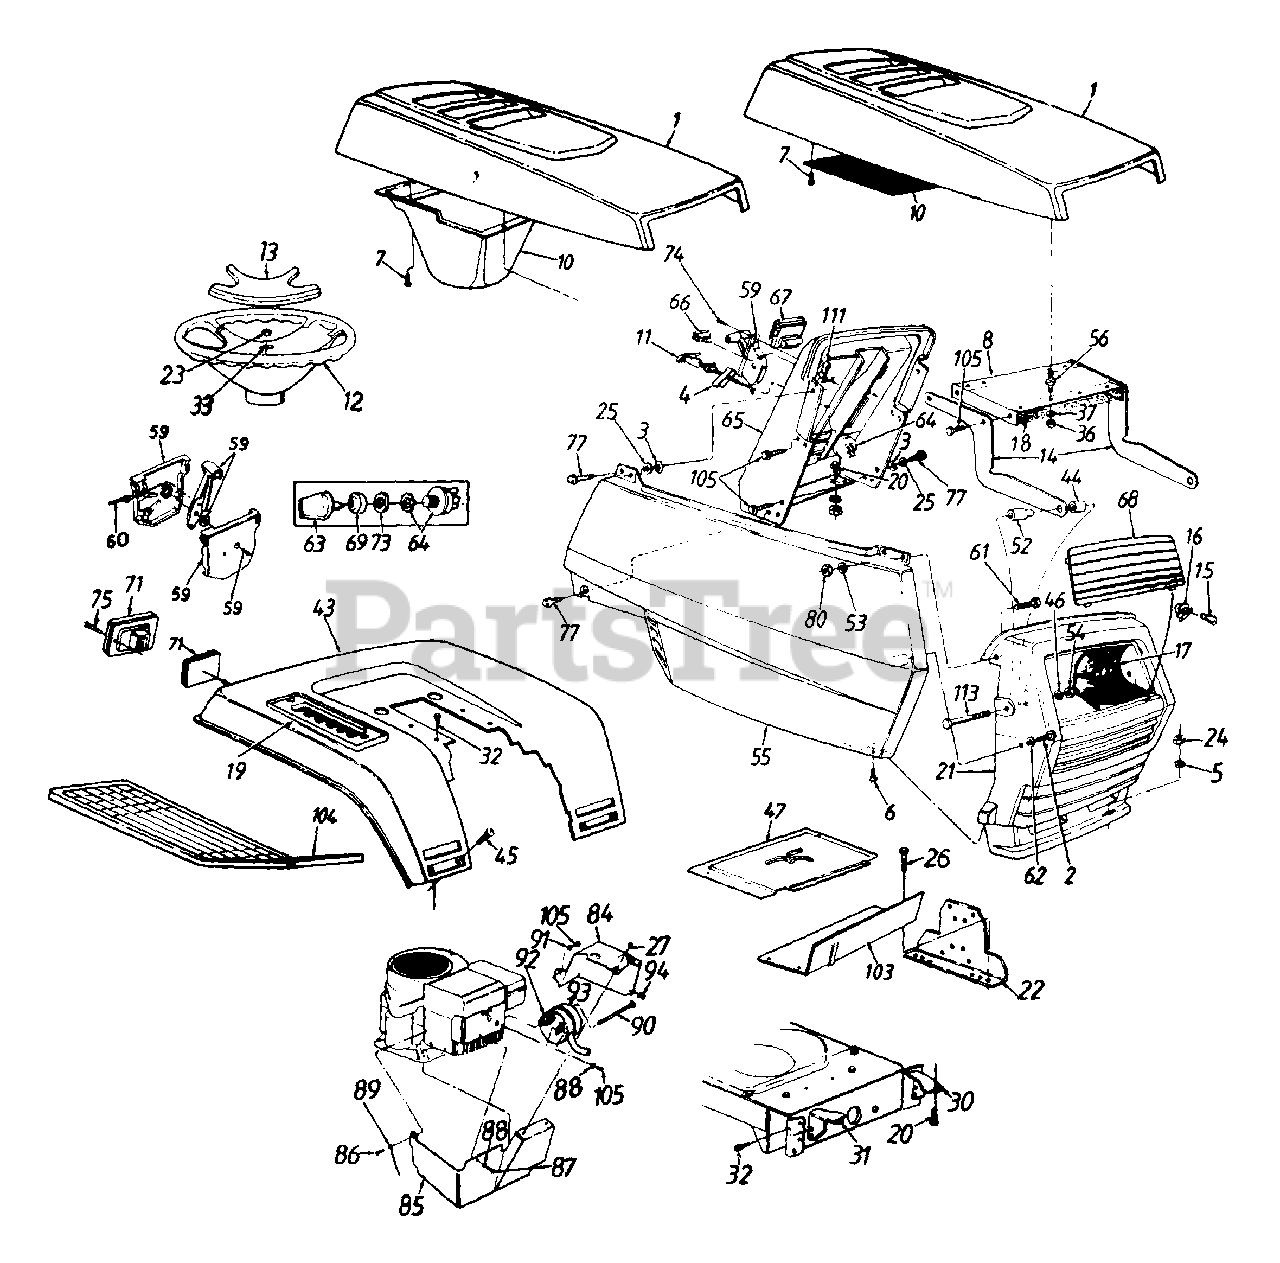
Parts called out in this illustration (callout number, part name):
1	Hood Ass'y.
3	Bolt Retainer 1/4" I.D.
4	Retainer Clip
5	Fl-Wash. .34" I.D. x .68"
6	Truss Mach. B-Tap Scr. #10 x .5" Lg.
7	Hex Wash Hd. AB-Tap Scr. #8 x .5" Lg.
11	Choke Control 29" Lg.
12	Steering Wheel
13	Steering Wheel Cap
14	Hood Hinge
15	Lamp
16	Twist Lock - Lamp Socket
17	Reflector - Headlight
18	Foam Seal
24	Hex Nut 5/16-18 Thd.
25	Fl-Wash. 1/4" I.D. x .93" O.D.
26	Hex Wash. Hd. B-Tap Scr. 5/16-18 x .5" Lg.
27	Hex B-Tap Scr. #10 x .38" Lg.
30	Grille Mount Brk't. - L.H.
31	Grille Mount Brk't. - R.H.
32	Hex Wash. Hd. AB-Tap Scr. 5/16 x .75" Lg.
33	Bell-Wash. .345" I.D. x .88"
36	Hex Nut 1/4-20 Thd.
37	Bell-Wash. .265" I.D. x .75"
43	Rear Fender
44	Spacer .33" I.D. x .625" O.D.
45	Carriage Bolt 1/4-20 x .50" Lg.
46	Fl-Wash. .328" I.D. x .68" O.D.
47	Transmission Panel
52	Shld. Spacer .33" I.D.
53	Fl-Wash. .281" I.D. x .5" O.D.
54	Hex Cent. L-Nut 5/16-18 Thd.
55	Side Cover - R.H.
56	Double Ended Stud 1/4-20 Thd.
59	Throttle Control Box Ass'y.
60	Throttle Control Wire 18.5" Lg.
61	Hex Bolt 1/4-20 x .62" Lg.
62	Fl-Wash. .281" I.D. x .73" O.D.
63	Ignition Key
64	Ignition Switch
65	Dash Panel
66	Light Switch
67	Ammeter
68	Lens
69	Ignition Switch Cap
71	Reflector
73	Ignition Switch Nut
74	Truss Mach. AB-Tap Scr. #10 x .5" Lg.
75	Truss Hd. AB-Tap Scr. #6 x .62" Lg.
77	Hex Wash. Hd. Tap Scr. 1/4 x .75" Lg.
80	Hex L-Nut 1/4-20 Thd.
84	Muffler Heat Shield - L.H.
85	Muffler Heat Shield - R.H.
86	Pan Hd. Mach. Scr. 5/16-18 x .75" Lg.
87	Hex Bolt 1/4-20 x 3/8" Lg.
88	Spr. Wash. .265" I.D.
89	Ground Wire
90	Shld. Bolt 7/16" Dia. x 3-5/8" Lg
91	L-Wash. 1/4" I.D.
92	Gasket
93	Muffler
94	Speed Nut #10-24 Thd.
105	Hex Tap Scr. 1/4-20 x .5" Lg.
111	Speed Nut 1/4-20 Thd.
113	Hex Bolt 5/16-18 x 2.75"
